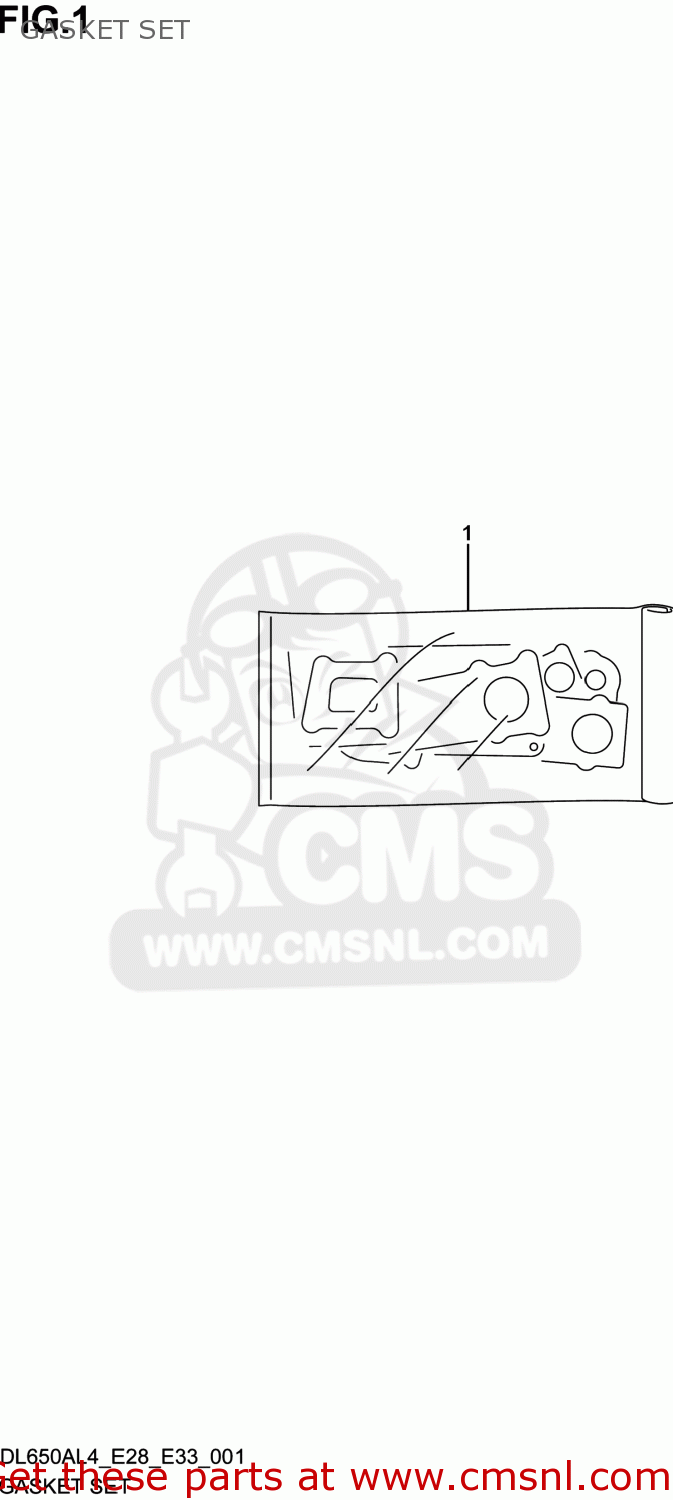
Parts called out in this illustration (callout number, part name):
1	GASKET SET (NAS)
2	GASKET,CYLINDER HEAD (NAS)
3	GASKET,CYLINDER HEAD COVER (NAS)
4	GASKET,CYLINDER FR (NAS)
5	GASKET,CYLINDER RR (NAS)
6	GASKET,CLUTCH COVER (NAS)
7	GASKET,MAGNETO COVER (NAS)
8	GASKET,TENSIONER ADJUSTER (NAS)
9	GASKET,EXHAUST PIPE (NAS)
10	WASHER,CYL HEAD COVER
